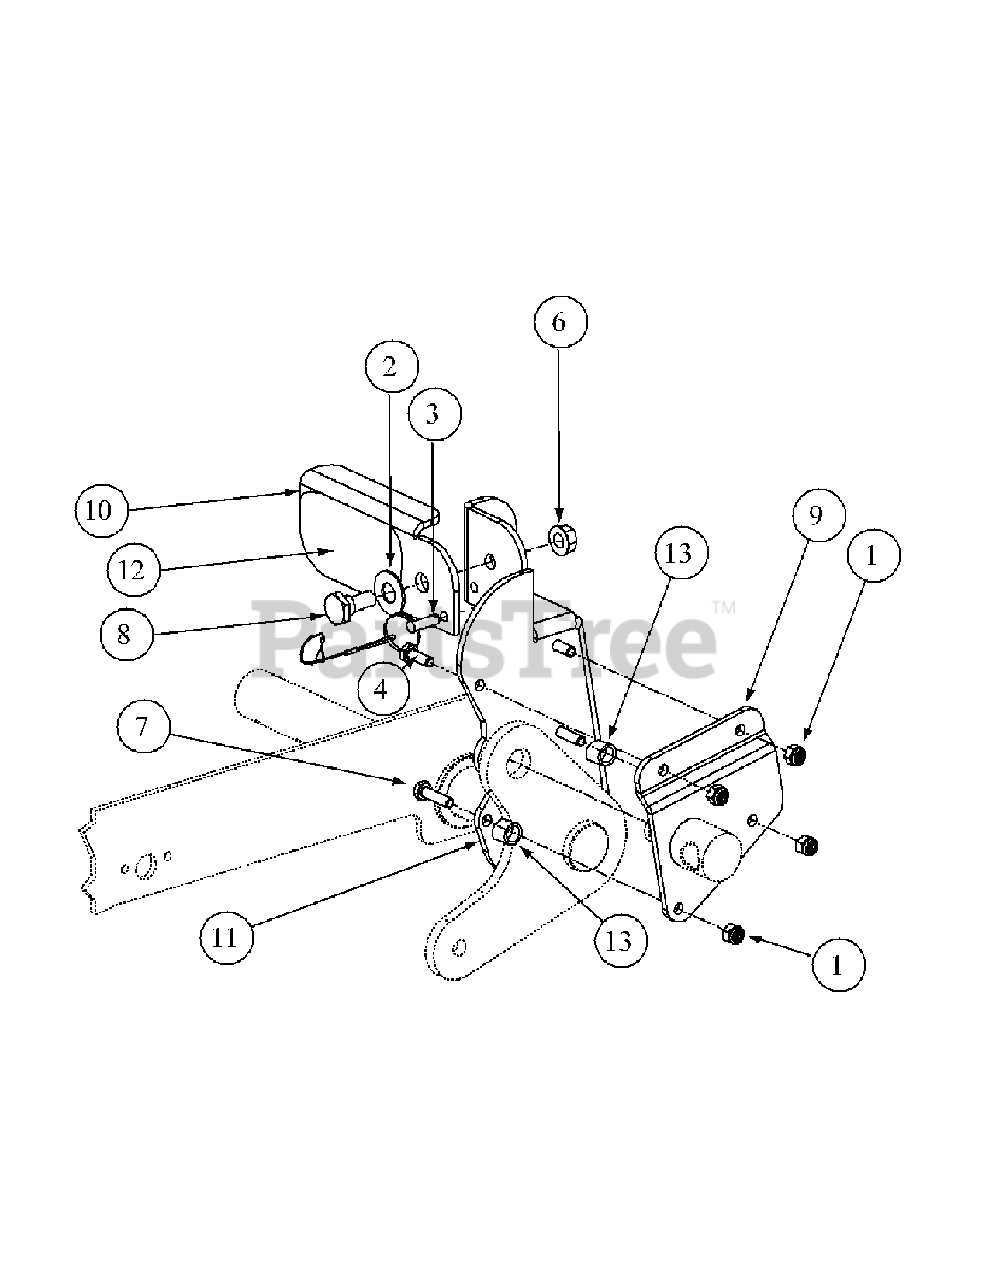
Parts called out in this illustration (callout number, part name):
1	Lock Nut, Nylon Insert, 1/4-20
2	Washer, 1/2 x 1 Shim
3	Detent Pin w/12" Lanyard
4	Hex Cap Screw, 1/4-20, .75
6	Hex Nut, Flange Lock 3/8-16
7	Hex Cap Screw, 1/4-20, 1.00
8	Shoulder Screw, .50 x .27 Lg., 3/8-16
9	Foot Lift Backup Pedal
10	Deck Foot Pedal Lift
11	Deck Foot Pedal Lift
12	Deck Foot Lift Pad
13	Turnbuckle Sleeve
